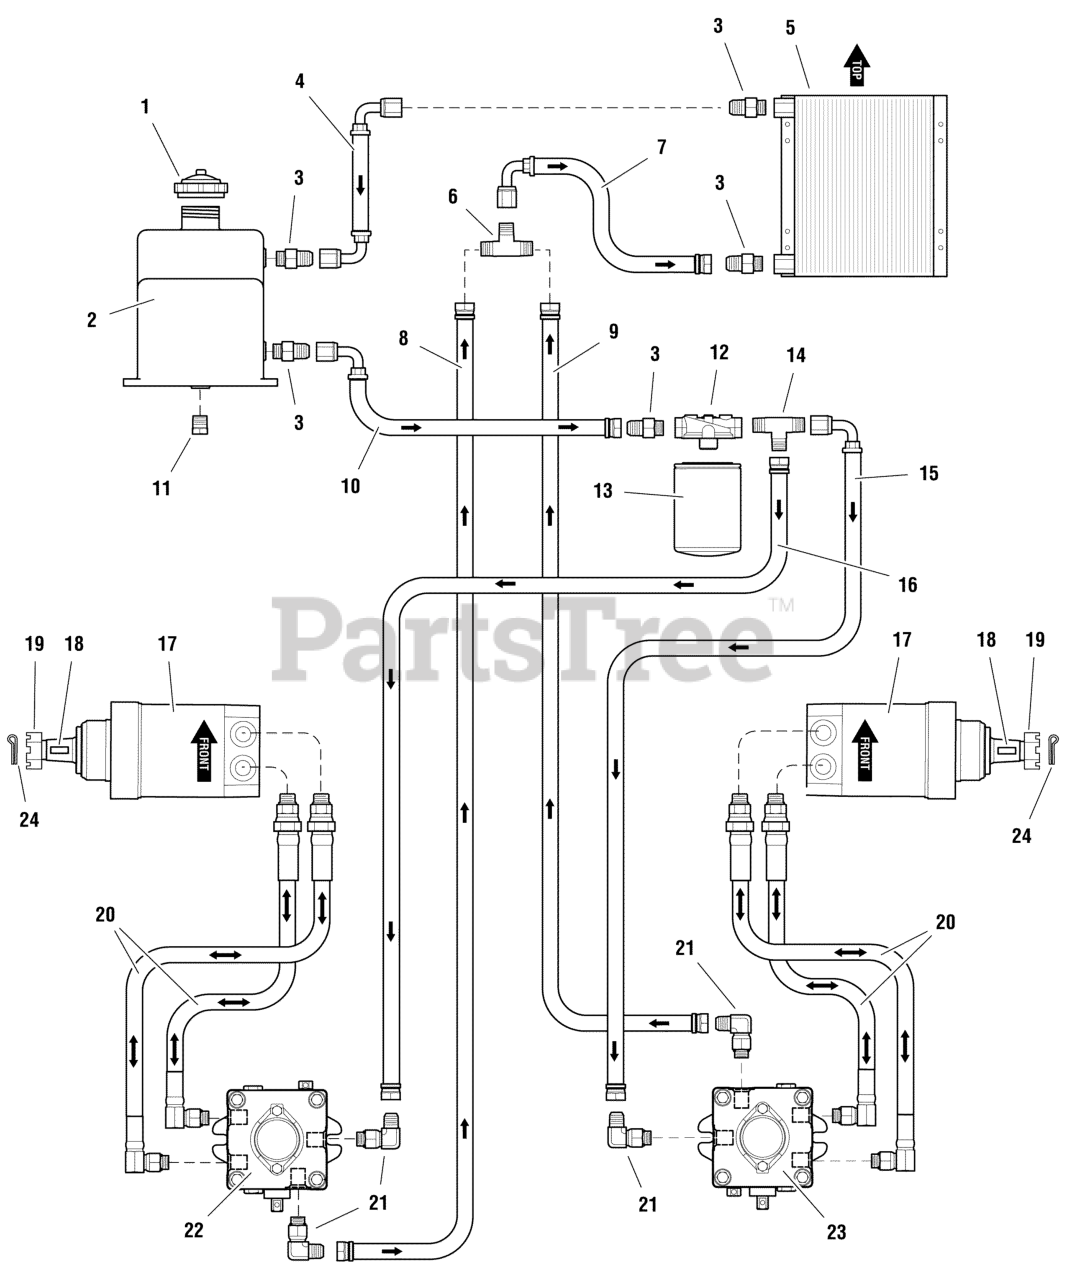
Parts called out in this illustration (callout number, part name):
1	CAP, Reservoir
2	HYDRAULIC OIL RESERVOIR
3	FITTING, NPT - JIC #8
4	HOSE ASSEMBLY (24")
5	OIL COOLER
6	FITTING, TEE, JIC #8
7	HOSE ASSEMBLY (13-1/2")
8	HOSE ASSEMBLY (25")
9	HOSE ASSEMBLY (29")
10	HOSE ASSEMBLY (10")
11	PLUG, 1/2" NPT
12	FILTER HEAD
13	FILTER, HYDRAULIC, SERVICE PART (PKG)
14	FITTING, TEE, JIC #8, NPT
15	HOSE ASSEMBLY (24")
16	HOSE ASSEMBLY (40")
17	HYDRAULIC WHEEL MOTOR, Complete
18	KEY
19	NUT, CASTLE, 1-20
21	FITTING, O-Ring, 90 Deg.
22	HYDRAULIC PUMP - LH
23	HYDRAULIC PUMP - RH
24	PIN, COTTER, 1/8" X 2"
